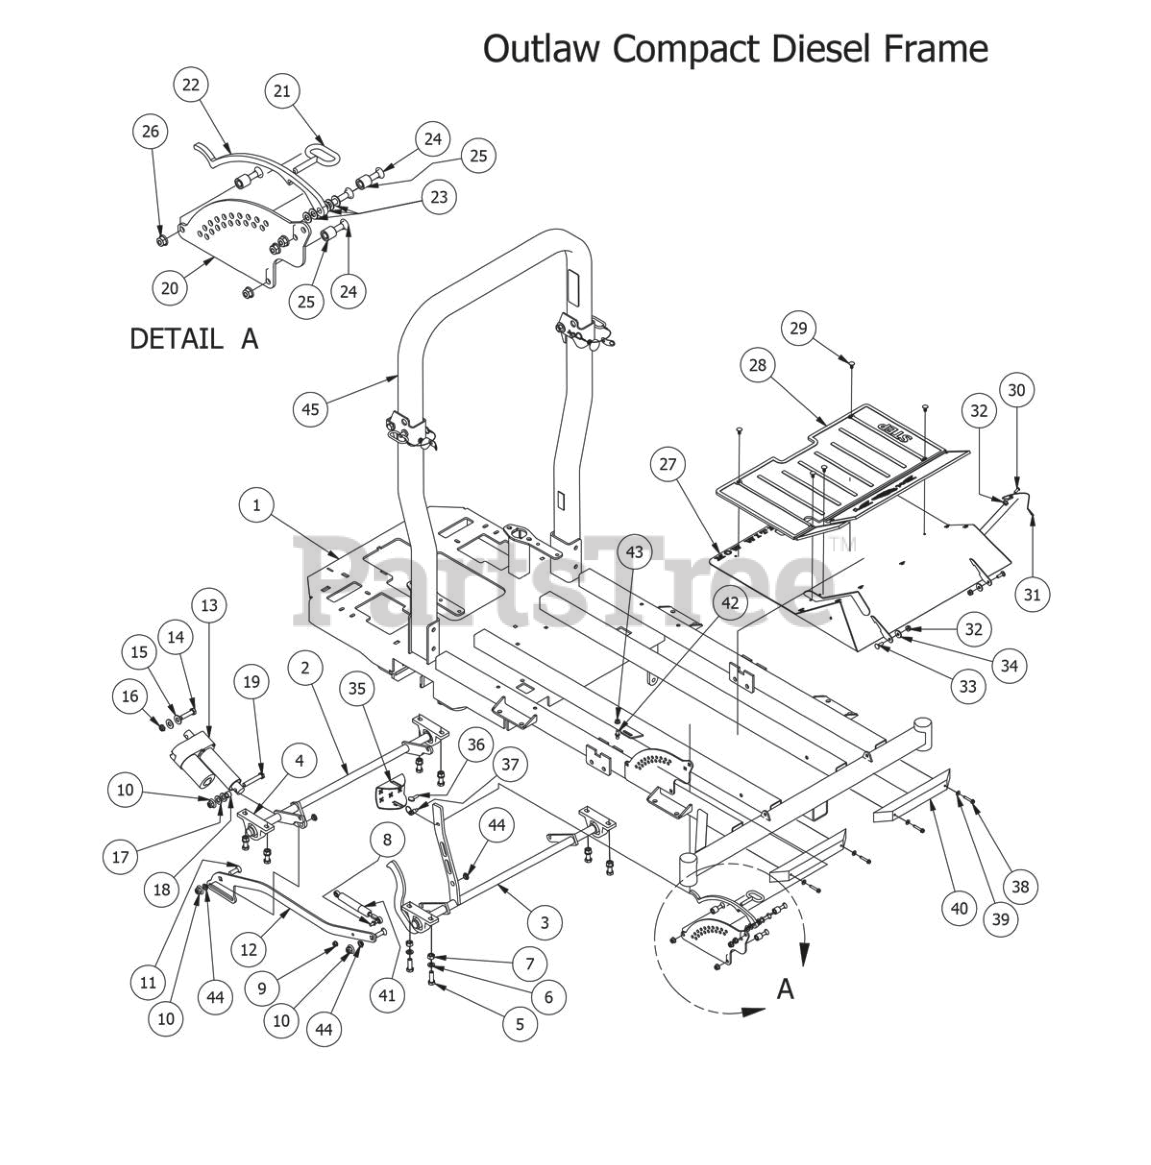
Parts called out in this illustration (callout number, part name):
1	Outlaw Diesel Frame 2012
2	Outlaw Actuator Bar (Rear)
3	Outlaw Front Actuator Bar Assembly
4	pillow block 2bolt sealmaster
5	1/2" x 1 1/2" Hex Bolt
6	1/2" Lock Washer
7	1/2" Hex Nut
8	10mm Damper Ball Stud-Steering
9	5/16" Flange Nut
10	1/2-13 Nylon Flange Nut-Orange
11	1/2 x 1-1/2 Carriage Bolt
12	Outlaw Susp Frame Linkage Bar
14	1/2-13x2 GR 5 Hex Bolt
15	1/2" Washer (Grade 8)
16	1/2" Nylcock Nut (1/2 Jam)
17	.635 ID Plastic Washer
18	1/2 x 1/2 Spacer
19	1/2-13 x GR 5 Hex Bolt Zinc
20	Outlaw Height Indicator Plate (Outer)
21	Deck height lever pin
22	Outlaw Deck Lever Lock
23	.390 x .750 x .062 Nylon Washer
24	3/8 x 1 3/4 Carriage Bolt
25	3/4 OD x 1/2 ID x 3\4 Length
26	3/8" Nylock Flange Nut
27	Outlaw Diesel Floor Panel
28	Foot Assist Floor Mat
29	Ratchet Fastener
30	1/4" x 5/8" BS C/S 18-8 SS
31	Floor board Cable W/ Swivel Ends
32	5/16-18 Nylon Flange Nut
33	5/16" x 1" Carriage Bolt
34	.360 ID Plastic Washer
35	Outlaw Deck Lift Pedal
36	5/16-18 x1 Thumb Screw Zinc
38	1/4" x 1 1/2" Self Tapping Screw
39	1/4" Flat Washer
40	14" Rubber Bumper
41	250lb Gas Spring -61" Deck
42	10mm Damper Ball Stud-Steering
43	5/16" Flange Nut w/Serrations
44	Actuator Bar Bushing-SF-1620-4
45	2 X 3 ROPS Fits All 2012 Diesel Models
